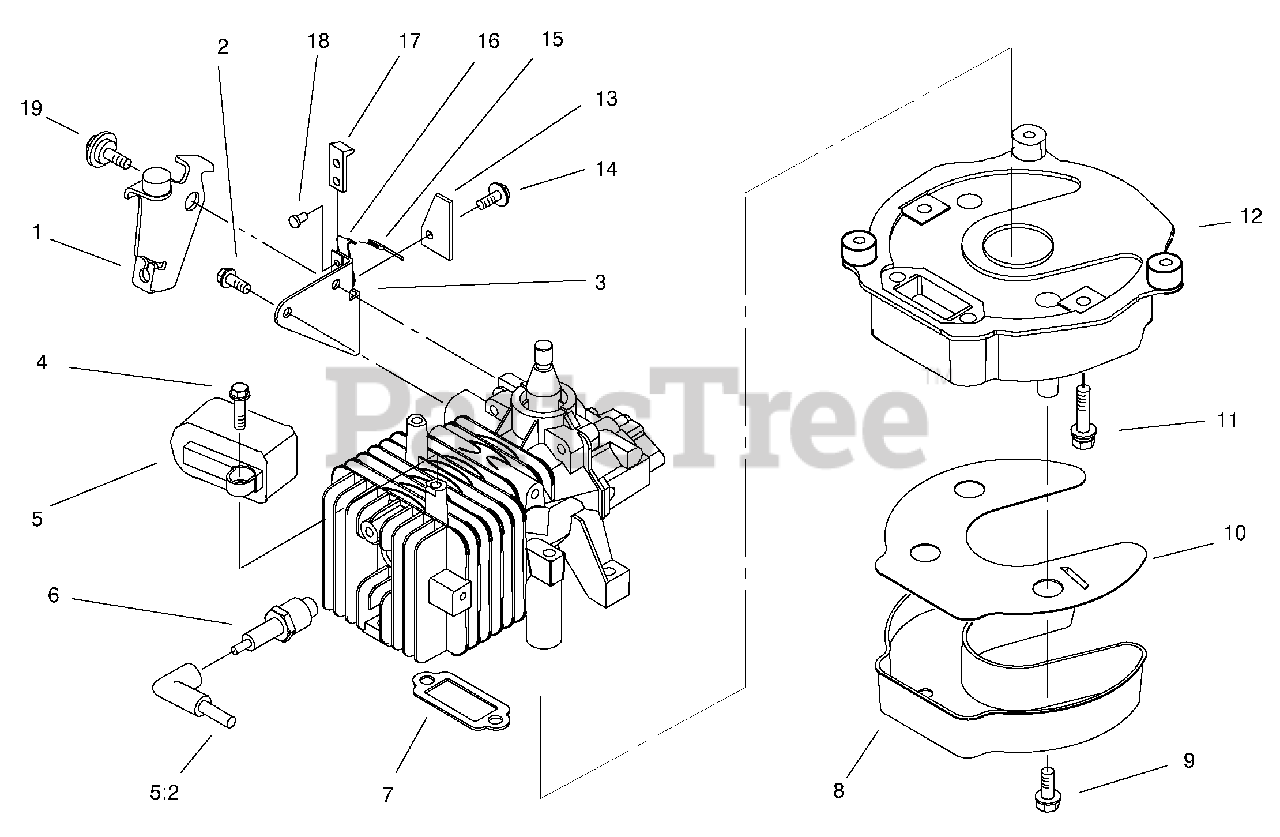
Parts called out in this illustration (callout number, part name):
1	Brake Plate ASM
2	Screw
3	Plate-Brake
5	Module-Ignition
5:2	Lead-Tension, High
6	Plug-Spark
7	Gasket-Exhaust
8	Cover-Muffler
10	Baffle-Muffler
12	Plate-Muffler
13	Stop-Strap, Ground
14	Screw Ev
15	Electrical Lead ASM
16	Strap-Ground
17	Strap-Insulation
18	Rivet-Plastic
19	Screw-Shoulder
